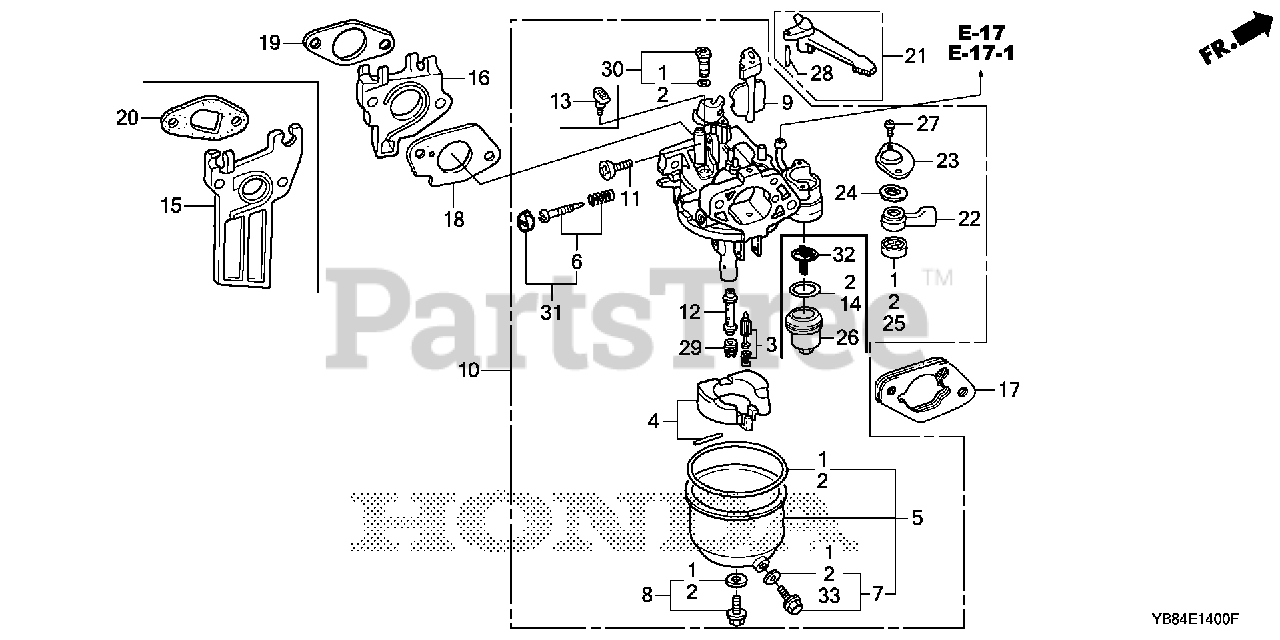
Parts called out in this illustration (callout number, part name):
1	GASKET SET
3	VALVE SET, FLOAT (SEAT NOT INCLUDED)
5	CHAMBER SET, FLOAT (CARBURETOR NO.)
7	SCREW SET, DRAIN
8	SCREW SET
9	CHOKE SET (CARBURETOR NO.)
10	CARBURETOR ASSY. (BE66D B)
11	SCREW, THROTTLE STOP
12	NOZZLE, MAIN (CARBURETOR NO.)
15	INSULATOR, CARBURETOR
17	SPACER, CARBURETOR
18	GASKET, CARBURETOR
20	GASKET, INSULATOR
21	LEVER, CHOKE (STD)
22	LEVER, PETCOCK (CARBURETOR NO.)
23	PLATE, LEVER SETTING
24	SPRING, PETCOCK LEVER
25	GASKET, PETCOCK (CARBURETOR NO.)
27	SCREW, PAN (3X6)
27	SCREW, PAN (3X8) (CARBURETOR NO.)
28	PIN, SPRING (2X12)
29	JET, MAIN (#68)
29	JET, MAIN (#70)
29	JET, MAIN (#65)
30	JET SET, PILOT (#35) (CARBURETOR NO.)
31	SCREW SET, PILOT (CARBURETOR NO.)
